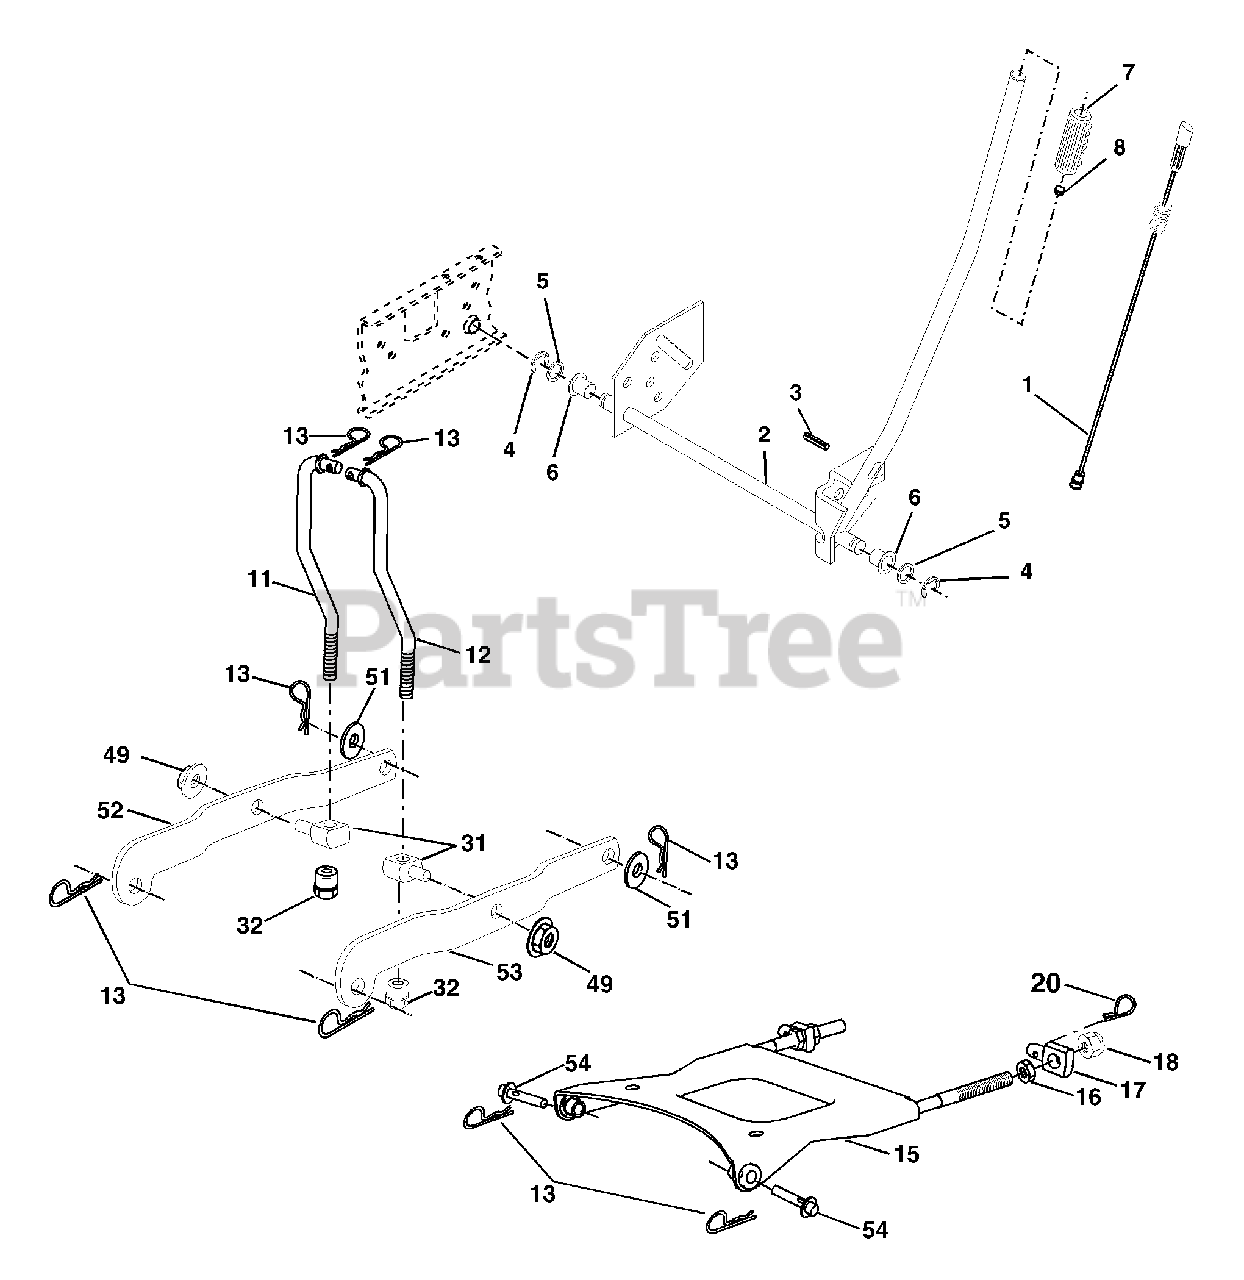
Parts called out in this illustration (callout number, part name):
1	Wire Asm Inner W/plunger 17 32
2	Shaft Asm Lift LH Inf Hgt P/L
3	Pin Groove 1 500 Zinc
4	E Ring #5133-62
5	Washer 21/32 x 1 x 21 Ga.
6	Bearing Nylon Blk 629 Id
7	Grip Handle
8	Button Plunger
11	Link Lift LH
12	Link Lift RH
13	Retainer Spring
15	Plate Asm Suspension Front
16	Nut Jam Hex 1/2-13 unc
17	Trunnion Blk Zinc
18	Nut Lock W/wsh 1/2-13 unc
20	Retainer Spring
31	Trunnion Suspension Arm
32	Nut Lift Link 7/16-20
49	Nut Hex Flange Lock
51	Washer 17/32 x 7/8 x 16 Ga.
52	Arm Suspension Rear LH
53	Arm Suspension Rear RH
54	Pin Flange
